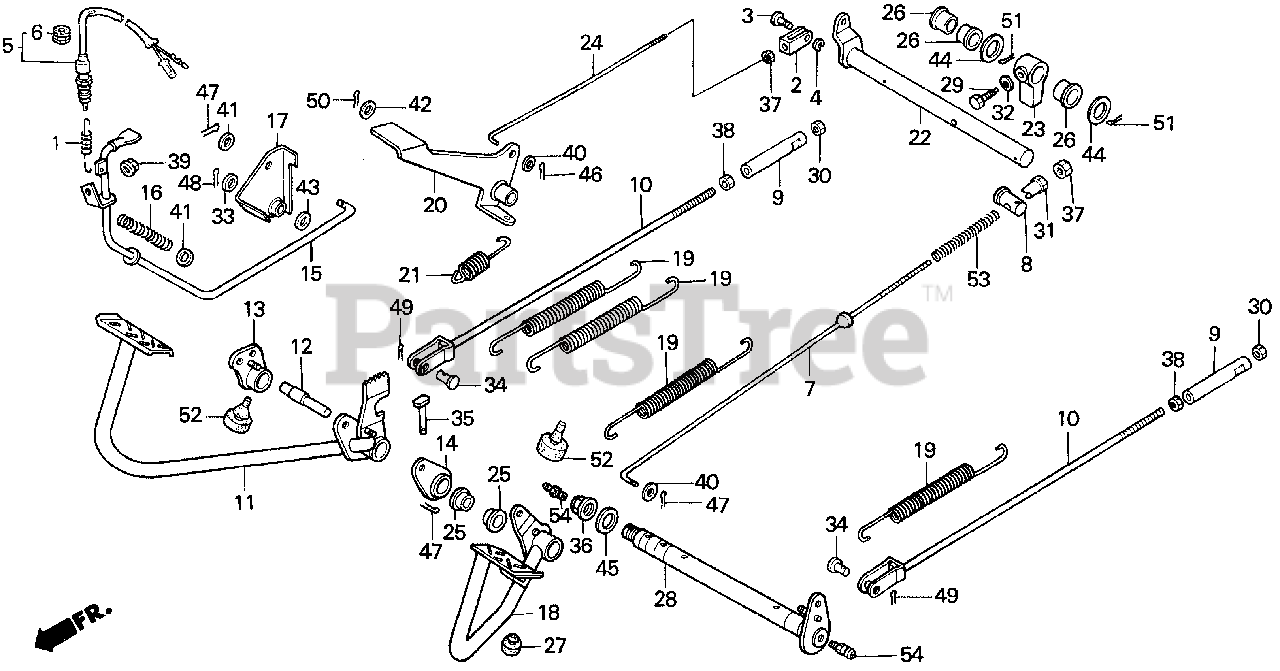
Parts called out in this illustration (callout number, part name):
1	SPRING, GOVERNOR
5	SWITCH ASSY., PARKING BRAKE
6	GROMMET, WIRE HARNESS
7	ROD, CLUTCH
8	JOINT, BRAKE ARM
9	JOINT (8MM)
10	ROD B, RR. BRAKE
11	PEDAL, BRAKE
12	BAR, EQUALIZER
13	ARM, R. EQUALIZER
14	ARM, L. EQUALIZER
15	LEVER, PARKING BRAKE
16	SPRING, PARKING BRAKE LEVER
17	ARM, PARKING BRAKE STOPPER
18	PEDAL, CLUTCH
19	SPRING, CLUTCH PEDAL
25	BUSH, BRAKE PEDAL
27	RUBBER B, STOPPER
28	SHAFT, BRAKE
30	NUT, HEX. (8MM)
31	NUT, ADJUSTING
33	WASHER (12.2X26) (NOT AVAILABLE)
34	PIN (8X17.5)
35	PIN, BRAKE SHAFT
36	NUT, STEERING SHAFT
37	NUT, HEX. (6MM)
38	NUT, HEX. (8MM)
39	NUT, FLANGE (6MM)
40	WASHER, PLAIN (6MM)
41	WASHER, PLAIN (8MM)
43	WASHER, FLAT (12MM)
45	WASHER, PLAIN (18MM)
47	PIN, COTTER (2.0X15)
48	PIN, COTTER (2.0X22)
48	PIN, COTTER (2.0X35)
49	PIN, COTTER (2.5MM)
52	RUBBER B, STAND STOPPER
53	SPRING A, BRAKE ROD
54	FITTING, GREASE (A.76)
